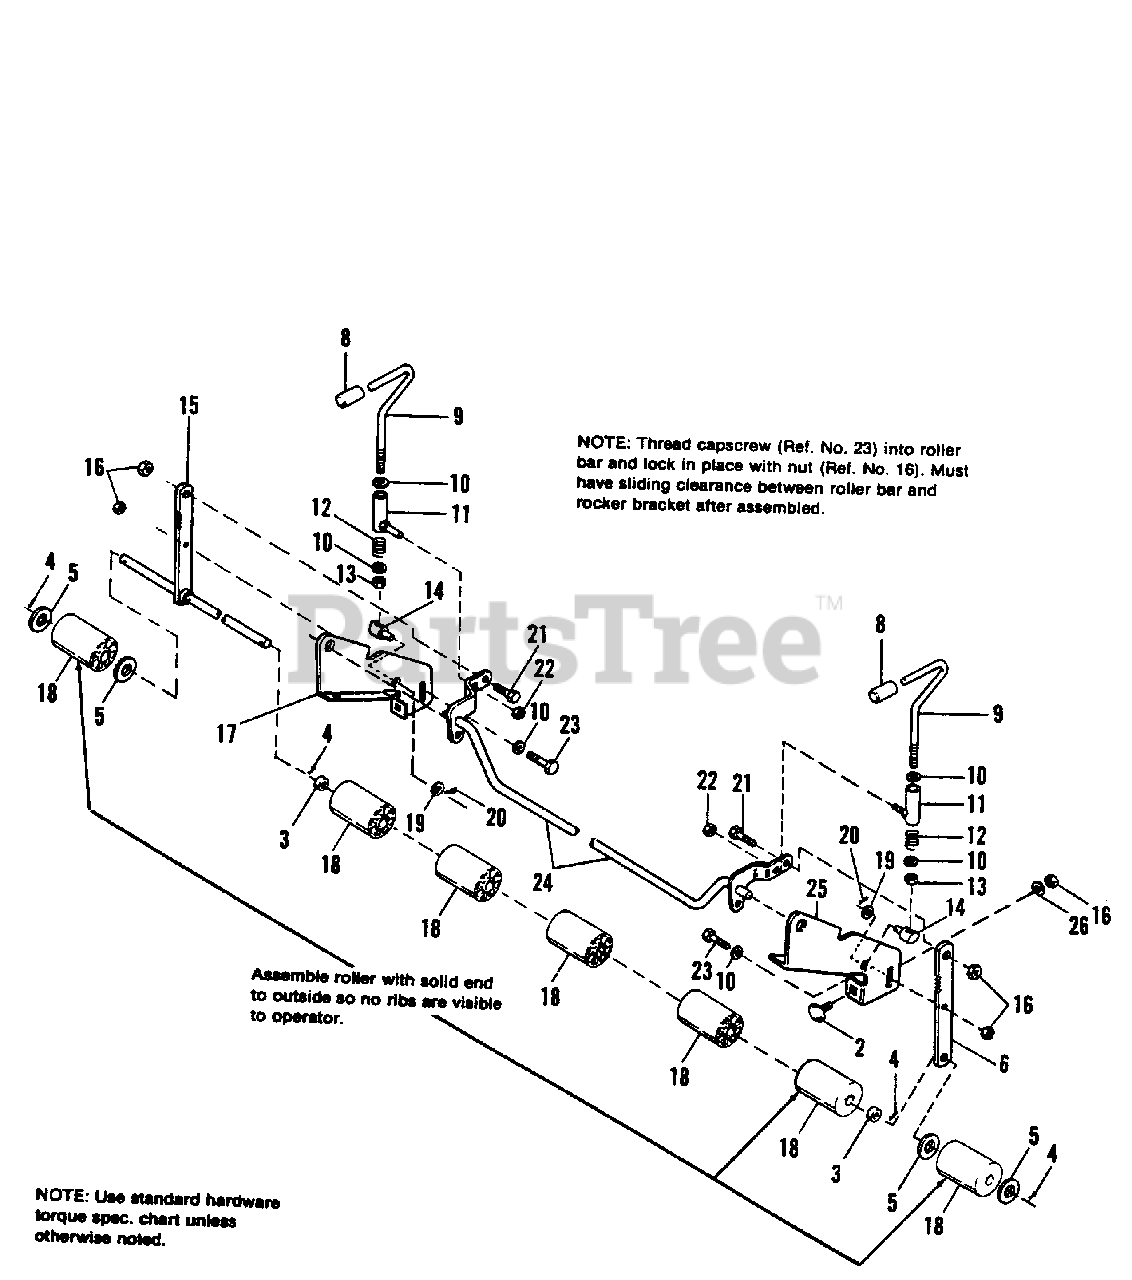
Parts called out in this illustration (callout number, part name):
2	CARRIAGE BOLT, 3/8-16 x 1
4	PIN, Cotter, 3/16 x 1
5	WASHER, Plain, 5/8
6	BAR, Roller
8	GRIP
9	HANDLE, Adjusting
10	WASHER, Plain, 3/8
11	SOCKET ASSY.
13	NUT, Hex, Jam, 3/8-16
15	SHAFT ASSY., Roller
16	NUT, Hex, Full, 3/8-16
17	BRACKET, Roller, R.H.
19	WASHER, Plain, 13/32 I.D.
20	PlN,Cotter, 3/32 x 3/4
21	CAPSCREW, Hex Hd., 3/8-16 x 1
22	LOCKNUT, Hex, Full, 3/8-16
23	CAPSCREW, Hex Hd., 3/8-16 x 1-1/4
24	ROCKER ARM ASSY
25	BRACKET, Roller, L H
26	LOCKWASHER, 3/8
